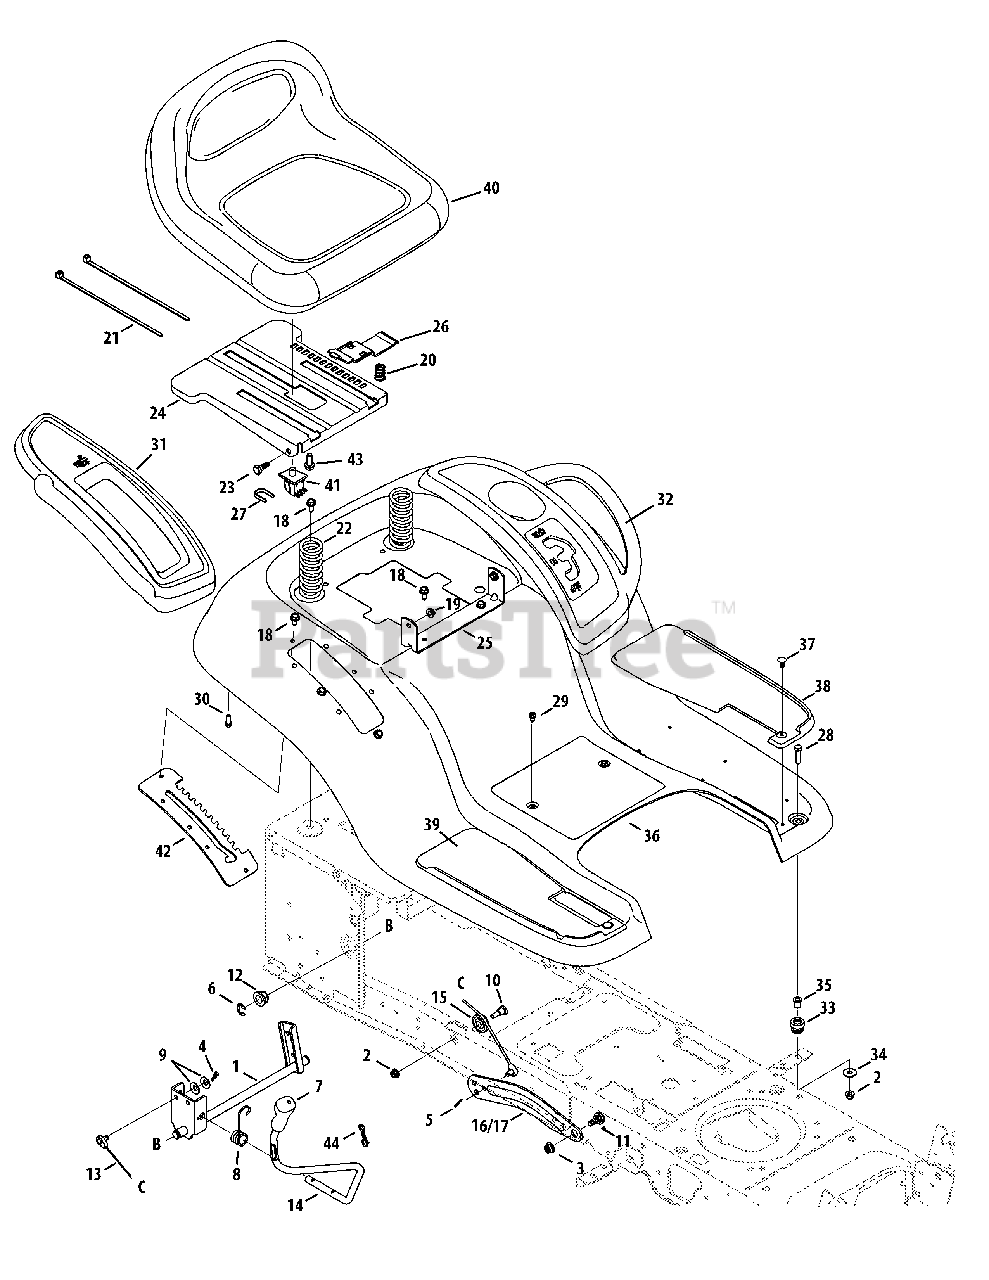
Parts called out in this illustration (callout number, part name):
1	Shaft Ass’y, Lift
2	Nut, Flange Lock, 5/16-18, Grf
3	Nut, Flange Lock, 3/8-16, Grf
4	Pin, Cotter, .072 Dia. x 1.13
5	Pin, Cotter, Bow-Tie 72
6	Ring, E Type, .625 Dia. Shaft
7	Grip, Handle, Cub, .50 ID
8	Spring, Torsion
9	Washer, Spring, .401 x .870 x .063
10	Screw, Shoulder, .437 x .470, 5/16-18
11	Bolt, Shoulder, .625, 3/8-16 (42")
12	Bearing, Hex Flange
13	Cable, Lift, 16.16
14	Handle, Lift
15	Pulley, Roller, Cable
16	Arm, Lift, 42" Rt RH
17	Arm, Lift, 42" Rt LH
18	Screw, Self-tapping, 5/16-18, .750,
19	Nut, Flange Lock, 5/16-18, Gr5, Sd Lk
20	Spring, Comp, .68 x 1.065 x .055
21	Cable, Tie, 3/16 x .05 x 7.4
22	Spring, Comprs, 1.5 x 3.9 x .200
23	Screw, Shoulder, .437 x .268, 5/16-18
24	Bracket, Mounting, Seat
25	Bracket, Pivot, Seat
26	Lever, Seat Adjustment
27	Clip, Retaining, Switch
28	Hex Screw, 5/16-18, 1.25, Gr5, Std
29	Screw, Self-tapping, 1/4-20, 0.500
30	Screw, HL, 1/4-15, 0.750,
31	Cover, Fender, RH
32	Cover, Fender, LH
33	Grommet, .4375 ID x .750
34	Washer, Flat .344 x 1.00 x .063
35	Spacer, Flange, .3125 x .4375 x .625
37	Clip, Ratchet, .250 Dia
38	Pad, Foot, LH
39	Pad, Foot, RH
40	Seat, Medium Back Cloth, Cub
41	Switch, Seat
42	Bracket, Lift, Manual PTO, 12 Pos
43	Hex Flange Bolt, 3/8/16, .875, Gr5
44	Pin, Cotter, Bow-Tie 72 (46" Decks)
